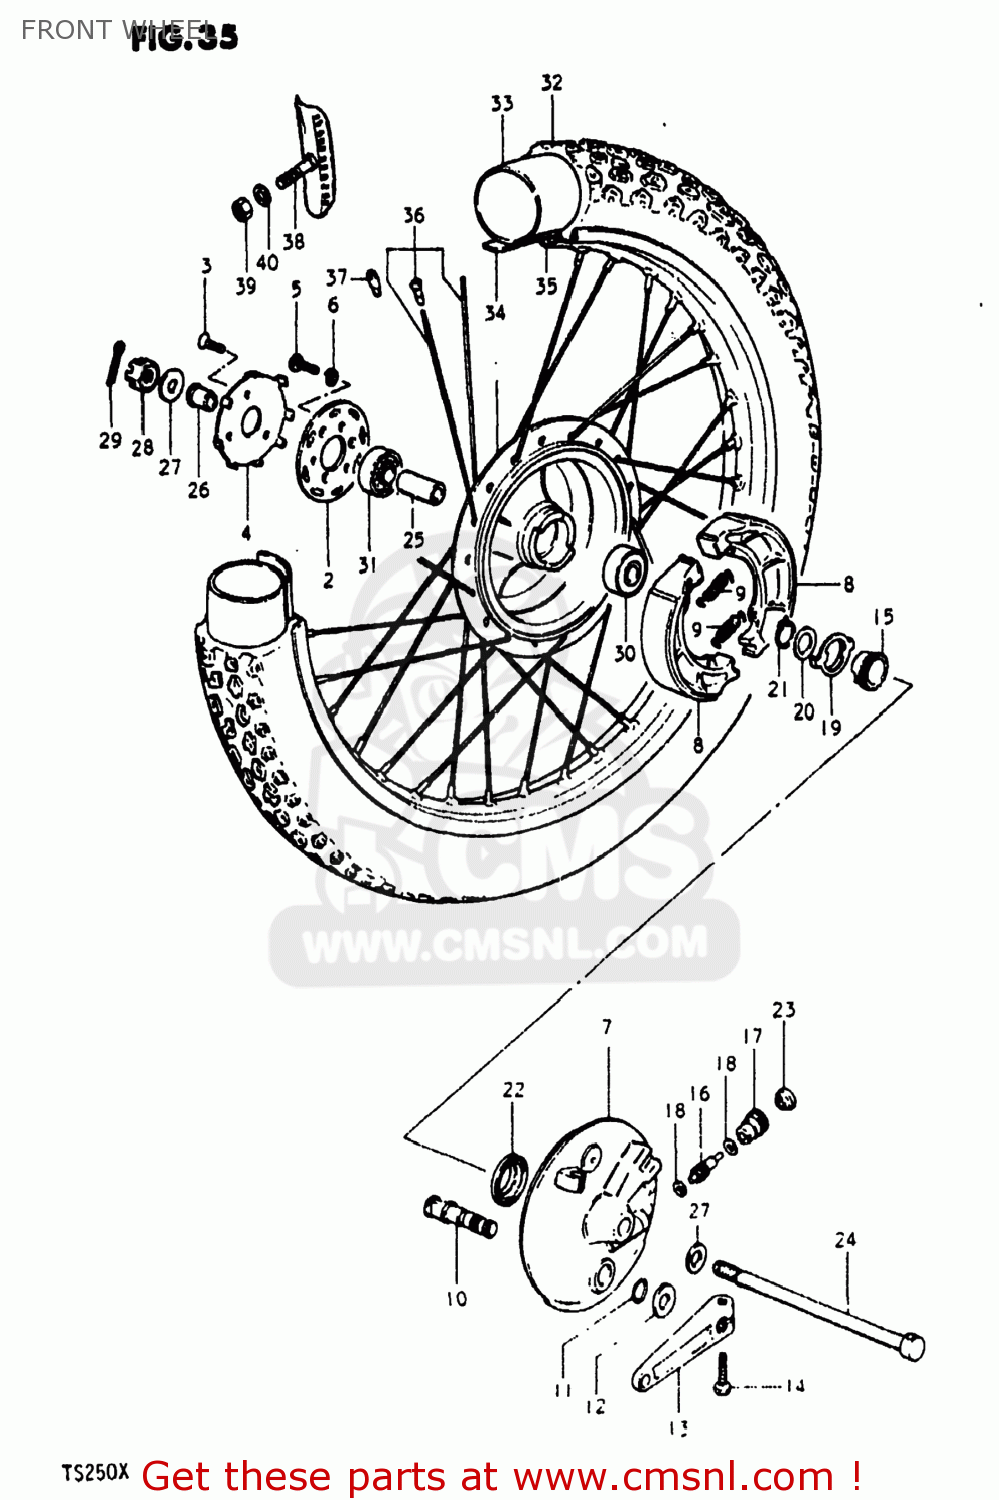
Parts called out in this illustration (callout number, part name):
1	DRUM,FRONT HUB
2	FLANGE,FR HUB,R
3	SCREW
4	RETAINER,FR HUB BEARING,R
5	BOLT, UPPER
6	LOCK WASHER
7	PANEL,FRONT HUB
8	SHOE,BRAKE (MCA)
9	SPRING
10	CAM,FRONT BRAKE
11	O-RING,BOSS
12	WASHER (15X24X1.6)
13	LEVER,FRONT BRAKE CAM
14	BOLT
15	GEAR,SPEEDOMETER
16	PINION,SPEEDOMETER
17	BUSHING,SPEEDOMETER PINION
18	WASHER (5.1X9X0.4)
19	DRIVER,SPEEDOMETER GEAR
20	WASHER(22.5X27X1)
21	CIRCLIP
22	SEAL,OIL(26X38X4)
23	SEAL,OIL(6X10X3)
24	AXLE,REAR
25	SPACER (12.6X19X52)
26	SPACER,FR AXLE,R
27	WASHER
28	NUT, REAR AXLE
29	COTTER PIN
30	BEARING
31	BEARING, RH
32	TIRE,FRONT
33	TUBE
34	PROTECTOR,WHEEL,INNER
35	RIM,FRONT WHEEL
36	SPOKE SET,FR
37	BALANCER,WHEEL (50G)
38	STOPPER,BEAD
39	NUT
40	WASHER
